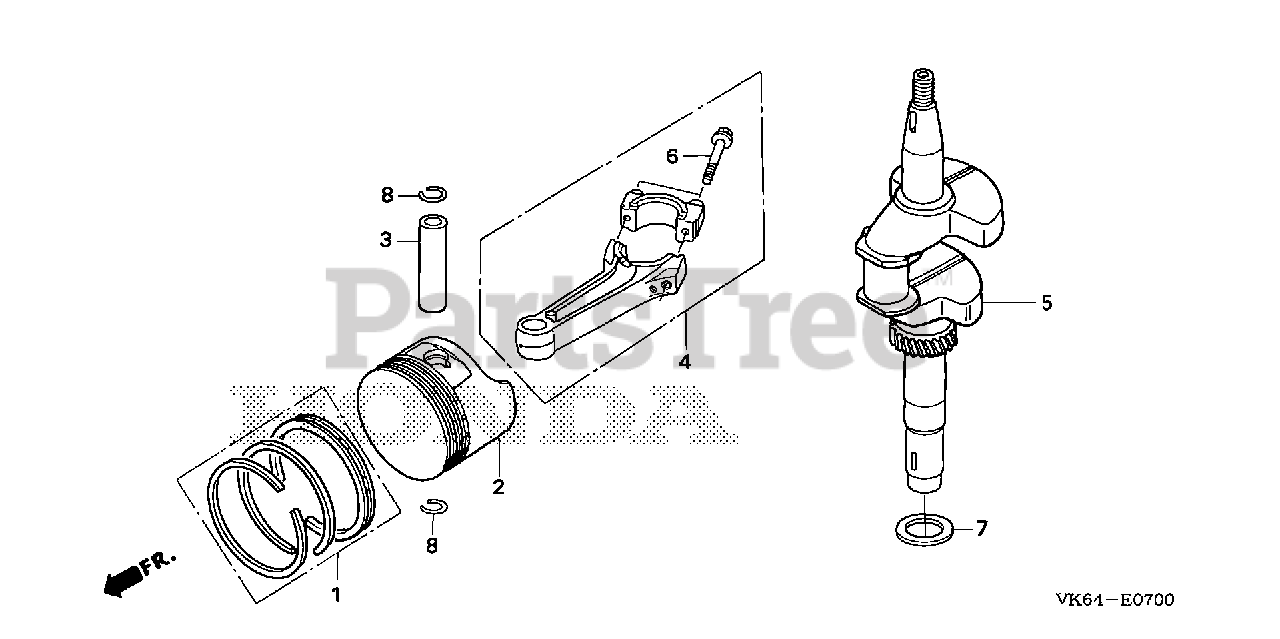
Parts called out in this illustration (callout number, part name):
1	RING SET, PISTON (STD) (FUJIAN DONGYA MACHINERY)
1	RING SET, PISTON (STD) (TPR)
1	RING SET, PISTON (STD) (RIKEN)
1	RING SET, PISTON (0.25) (TPR)
1	RING SET, PISTON (0.25) (RIKEN)
1	RING SET, PISTON (0.50) (TPR)
1	RING SET, PISTON (0.50) (RIKEN)
1	RING SET, PISTON (0.75) (FUJIAN DONGYA MACHINERY)
1	RING SET, PISTON (0.75) (TPR)
1	RING SET, PISTON (0.75) (RIKEN)
2	PISTON (STD) (JIALING-HONDA)
2	PISTON (0.25)
2	PISTON (0.50)
2	PISTON (0.75)
3	PIN, PISTON
4	ROD ASSY., CONNECTING
5	CRANKSHAFT
6	BOLT, CONNECTING ROD
7	WASHER, THRUST (25.6MM)
8	CLIP, PISTON PIN (18MM)
